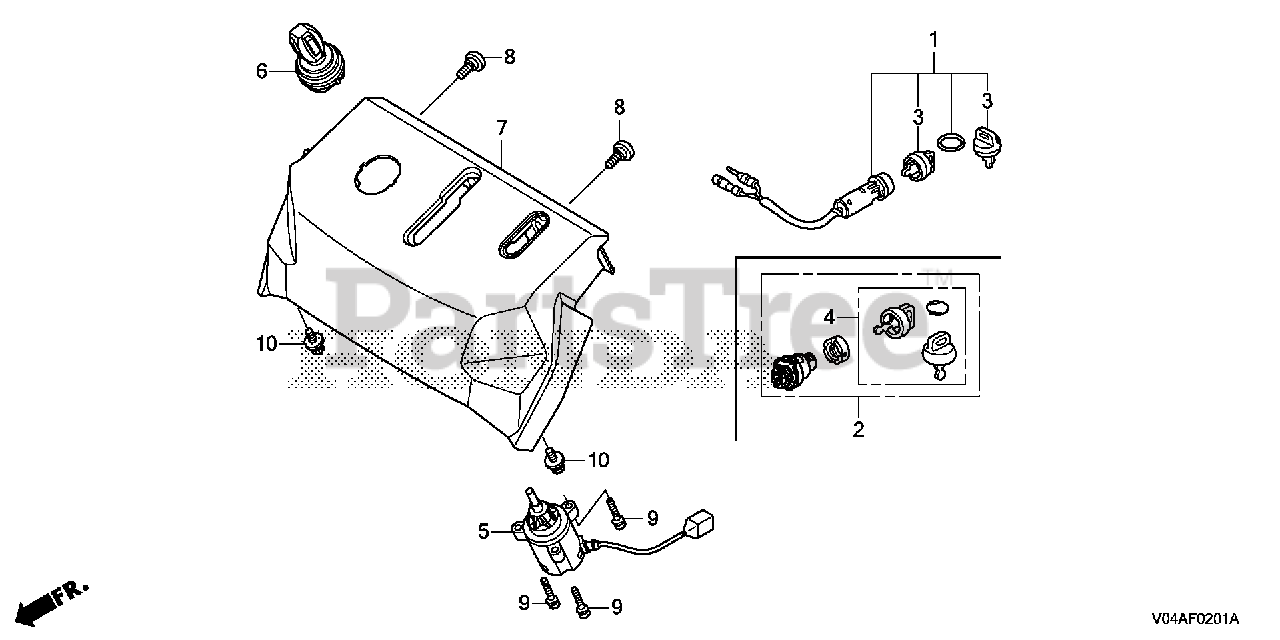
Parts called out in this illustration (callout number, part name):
2	SWITCH ASSY., COMBINATION
4	KEY ASSY., COMBINATION SWITCH
5	SWITCH ASSY., CHUTE CONTROL
6	BOOT, RUBBER
7	PANEL, CONTROL *NH296* (ALPS GRAY)
8	BOLT, CHUTE SETTING
9	BOLT-WASHER (5X20)
10	BOLT-WASHER (5X12)
